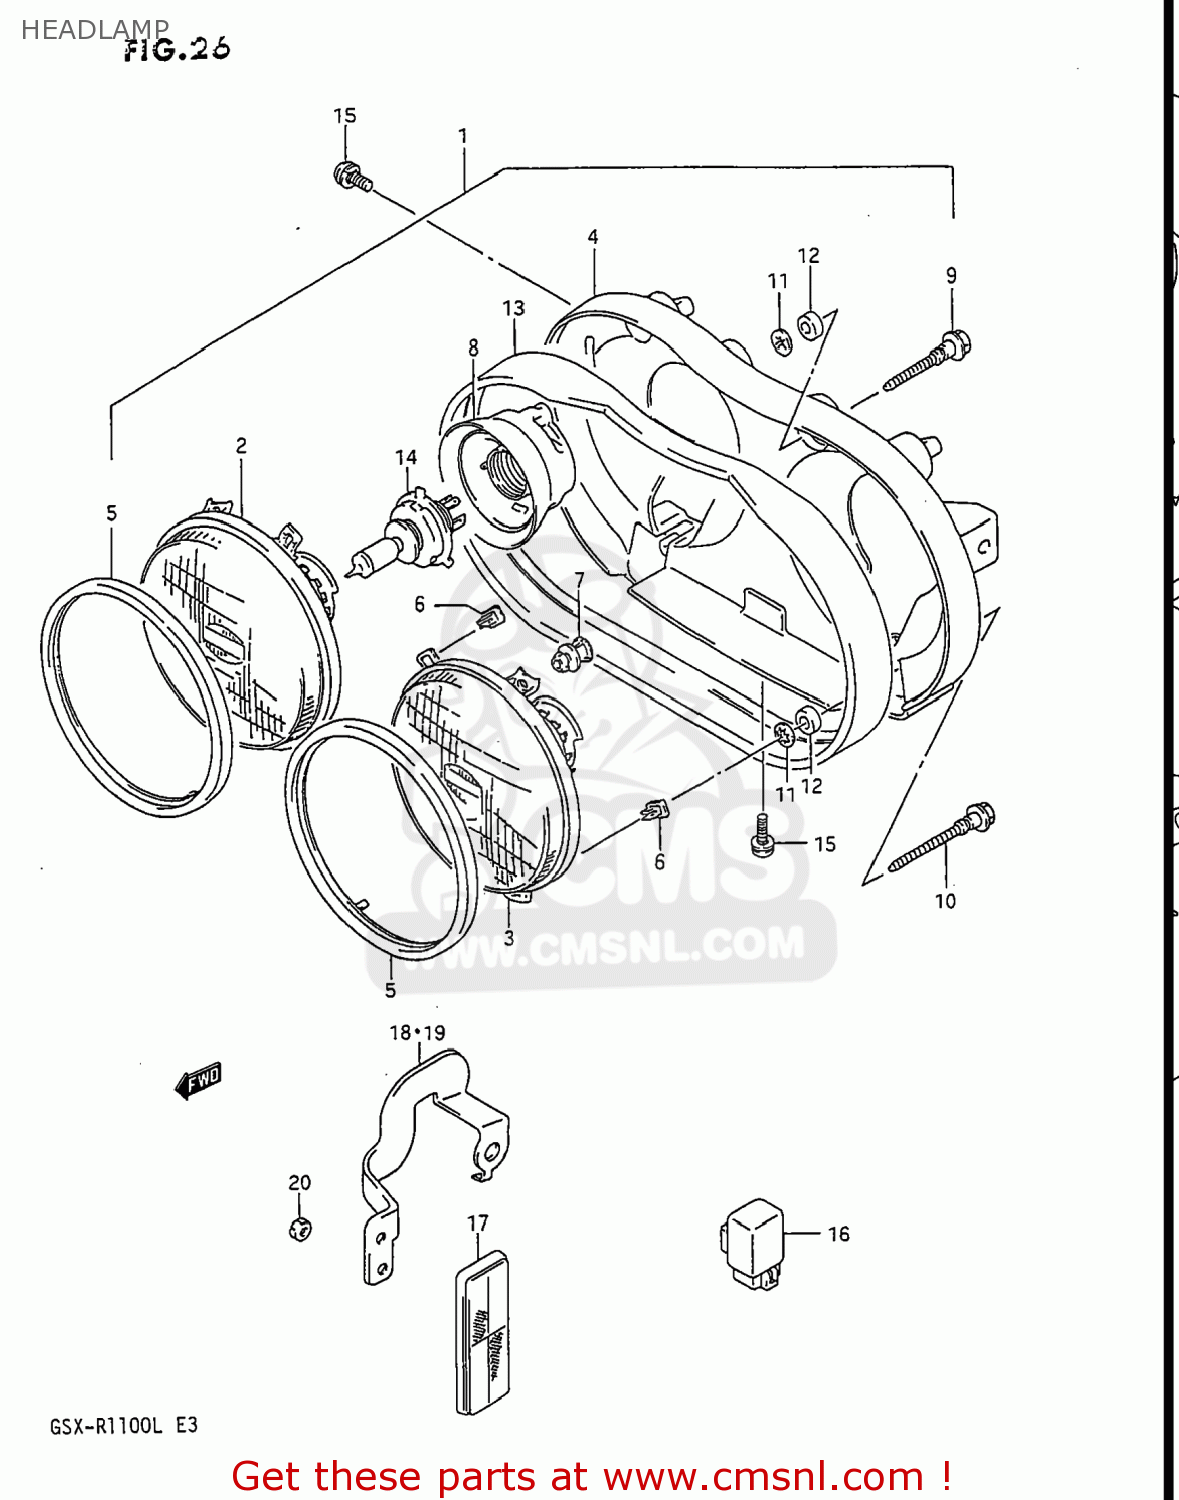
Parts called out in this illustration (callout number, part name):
1	HEADLAMP ASSEMBLY
2	LAMP UNIT,L
3	LAMP UNIT,R
4	HOUSING,HEAD LAMP
5	RING,RETAINING
6	NUT,HEADLAMP ADJUSTER
7	SCREW,SPHERICAL
8	COVER,SOCKET
9	SCREW,HEADLAMP ADJUST
10	SCREW,ADJUSTER
11	WASHER
12	BUSHING
13	GASKET,HEADLAMP HOUSING (NAS)
14	BULB(12V60/55W,H4)
15	SCREW
16	RELAY ASSY,HEADLAMP
17	REFLEX REFLECTOR ASSEMBLY
18	BRACKET,FR SIDE REFLECTOR,R
19	BRACKET,FR SIDE REFLECTOR,L
20	NUT
